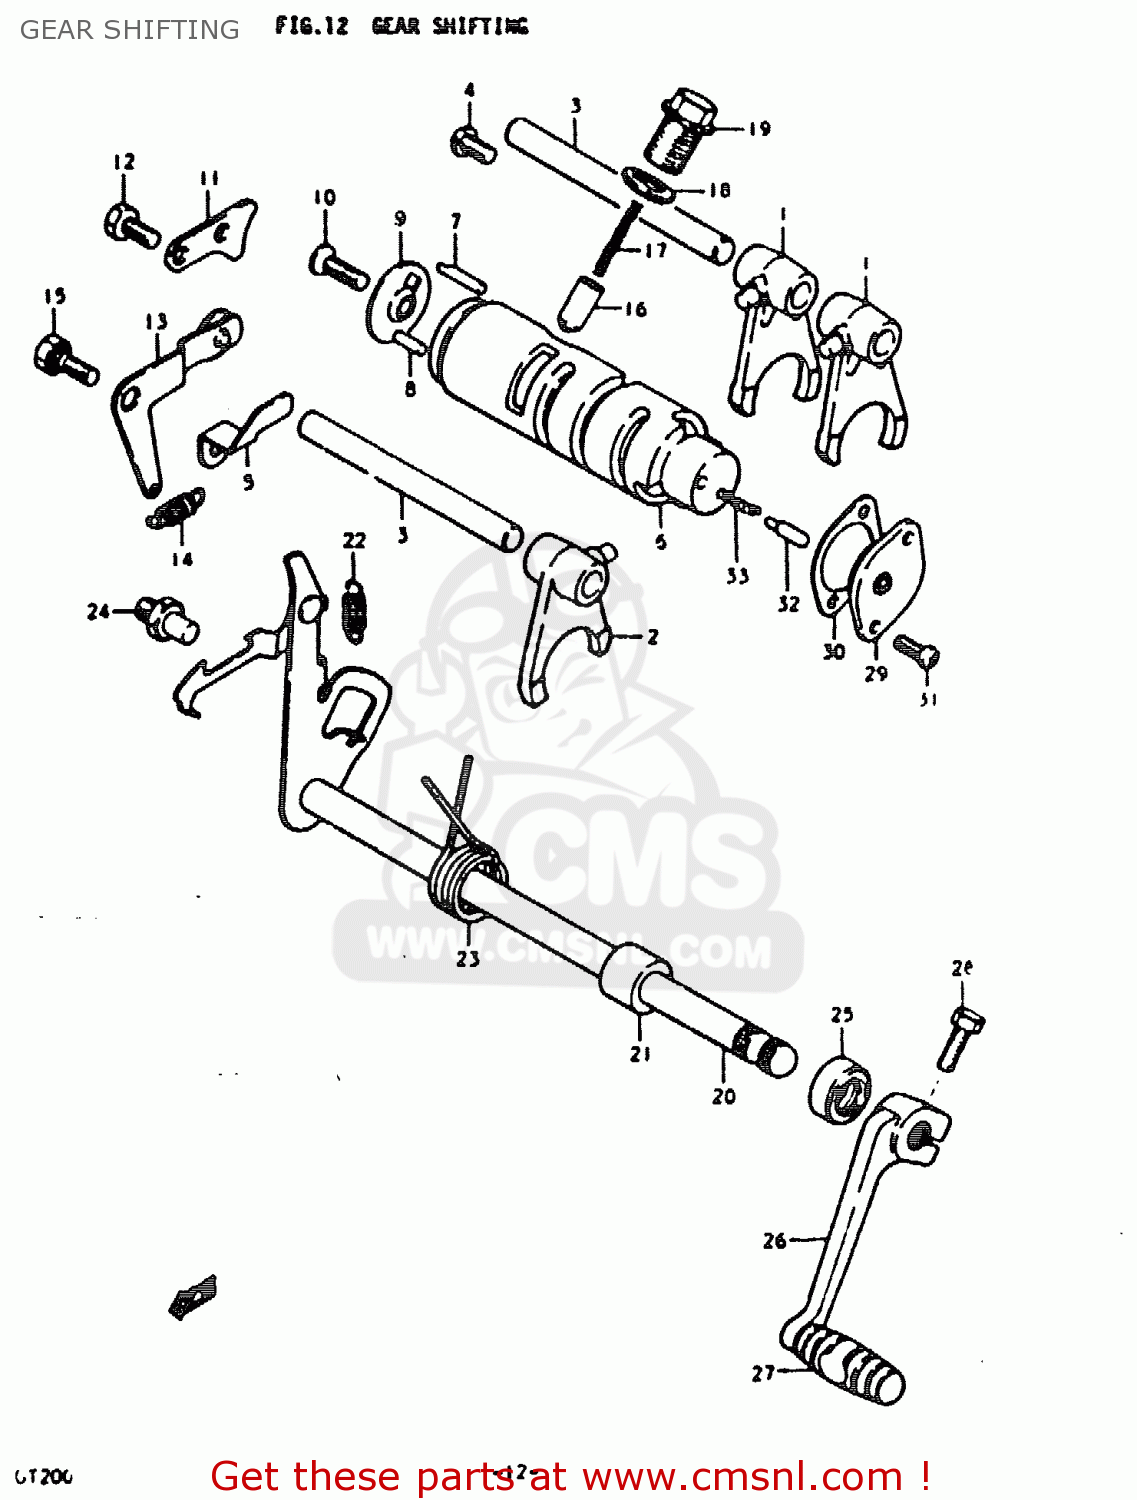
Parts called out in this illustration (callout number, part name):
1	FORK, GEAR SHIFTING NO.1
2	FORK, GEAR SHIFTING NO.2
3	SHAFT,GEAR SHIFT FORK
4	SCREW
5	STOPPER, FORK SHAFT NO.2
6	CAM, GEAR SHIFTING
7	PIN
8	ROLLER(4X13.8)
9	RETAINER, DRIVE PIN
10	SCREW
11	GUIDE,GEAR SHIFT CAM
12	BOLT
13	STOPPER, CAM NO.1
14	SPRING
15	BOLT(6X16.1)
16	STOPPER,GEAR SHIFTING
17	SPRING
18	GASKET(14X19.2X2) (NAS)
19	BOLT,GEAR SHAFT CAM STOPPER
20	SHAFT, GEAR SHIFTING
21	SPACER(12X20X15.3)
22	SPRING
23	SPRING
24	STOPPER,GEAR SHIFT CAM
25	OIL SEAL
26	LEVER ASSY, GEAR SHIFTING
27	RUBBER,GEAR SHIFT PEDAL
28	BOLT
29	BODY, GEAR SHIFTING SWITCH
30	GASKET (MCA)
31	SCREW
32	PIN(5X15.5)
33	SPRING
